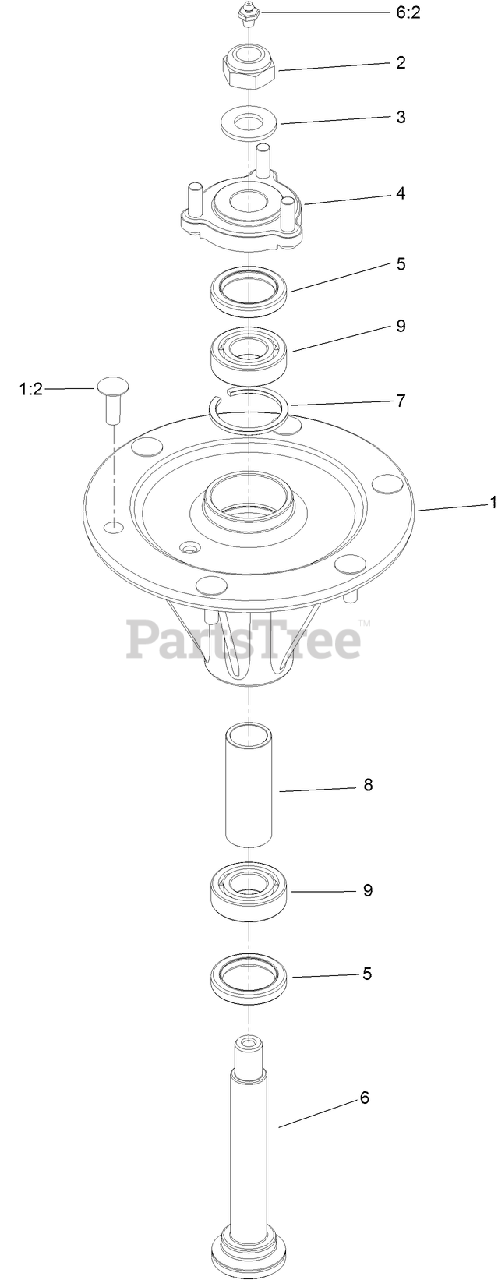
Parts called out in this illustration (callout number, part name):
1	SPINDLE HOUSING AND STUDS ASM
1:2	BOLT-RIBBED NECK
2	NUT-LOCK,NI LEFT HAND THREAD
3	WASHER
4	SPINDLE HUB ASM
5	SEAL-OIL
6	SHAFT-SPINDLE
6:2	FITTING-GREASE
7	SNAP RING
8	SPACER
9	BEARING-NOSEAL
